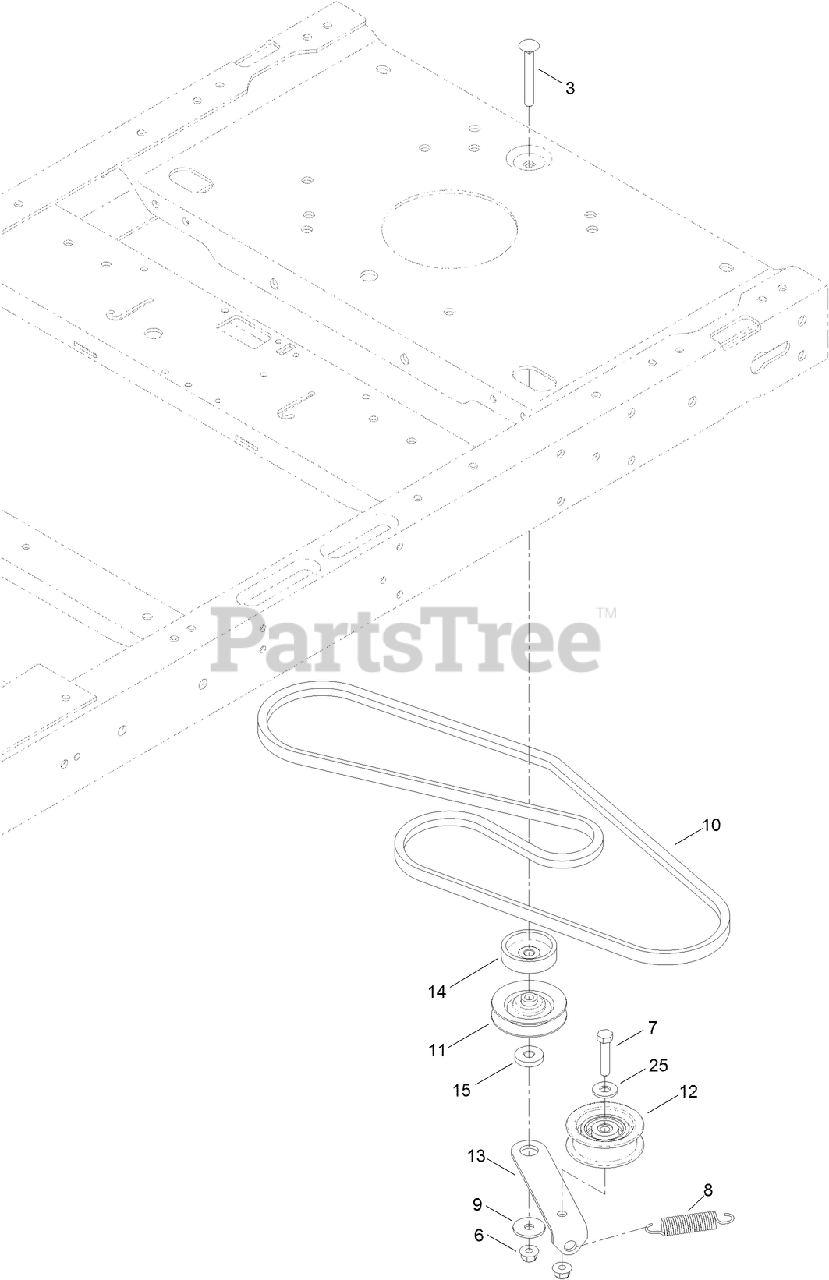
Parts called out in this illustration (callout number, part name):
3	SCREW-CARR
6	NUT-HF, NI
7	SCREW-HH
8	SPRING-RETURN, PEDAL
9	WASHER-PIVOT
10	V-BELT
11	PULLEY-IDLER
12	PULLEY-IDLER
13	ARM-IDLER
14	SPACER
15	SPACER-ARM, IDLER
25	WASHER-FLAT
